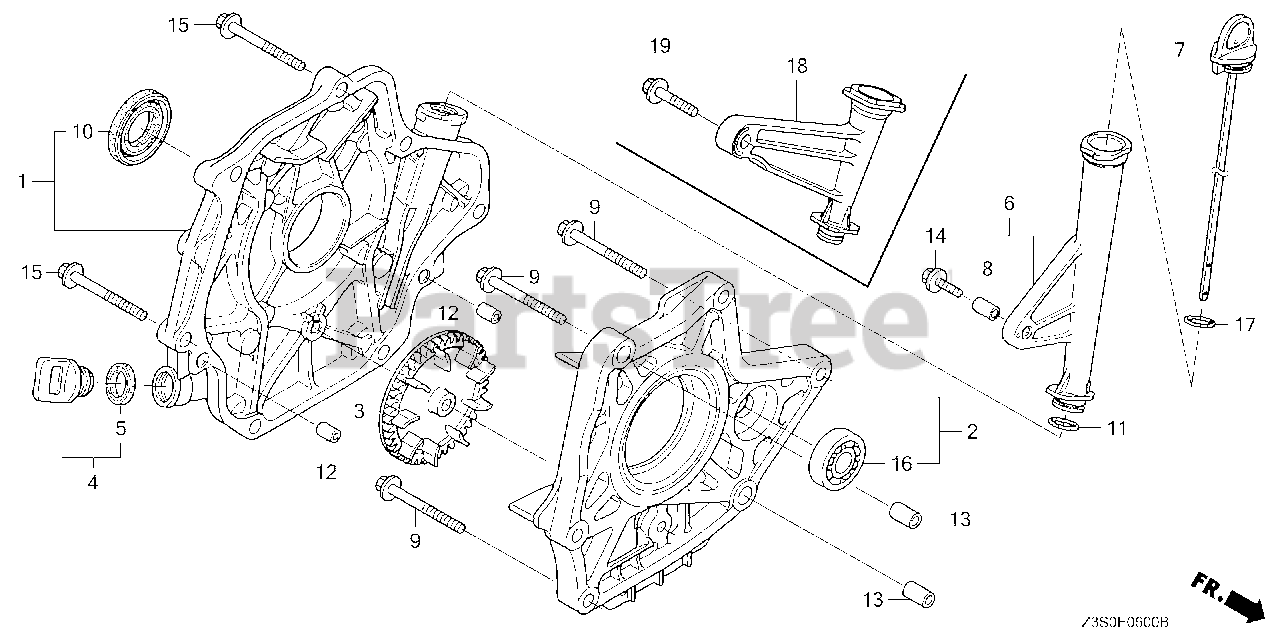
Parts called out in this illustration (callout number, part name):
1	COVER ASSY., CRANKCASE
2	HOLDER, BEARING
3	GEAR, SLINGER
4	CAP ASSY., OIL FILLER
5	GASKET, OIL FILLER CAP
7	DIPSTICK, OIL (123.5MM)
9	BOLT, FLANGE (8X45)
10	OIL SEAL (35X52X8)
12	PIN A, DOWEL (8X14)
13	PIN A, DOWEL (10X16)
15	BOLT, FLANGE (8X35)
16	BEARING, RADIAL BALL (6202)
17	O-RING (18.1X3.6)
17	O-RING (20.8X2.4)
